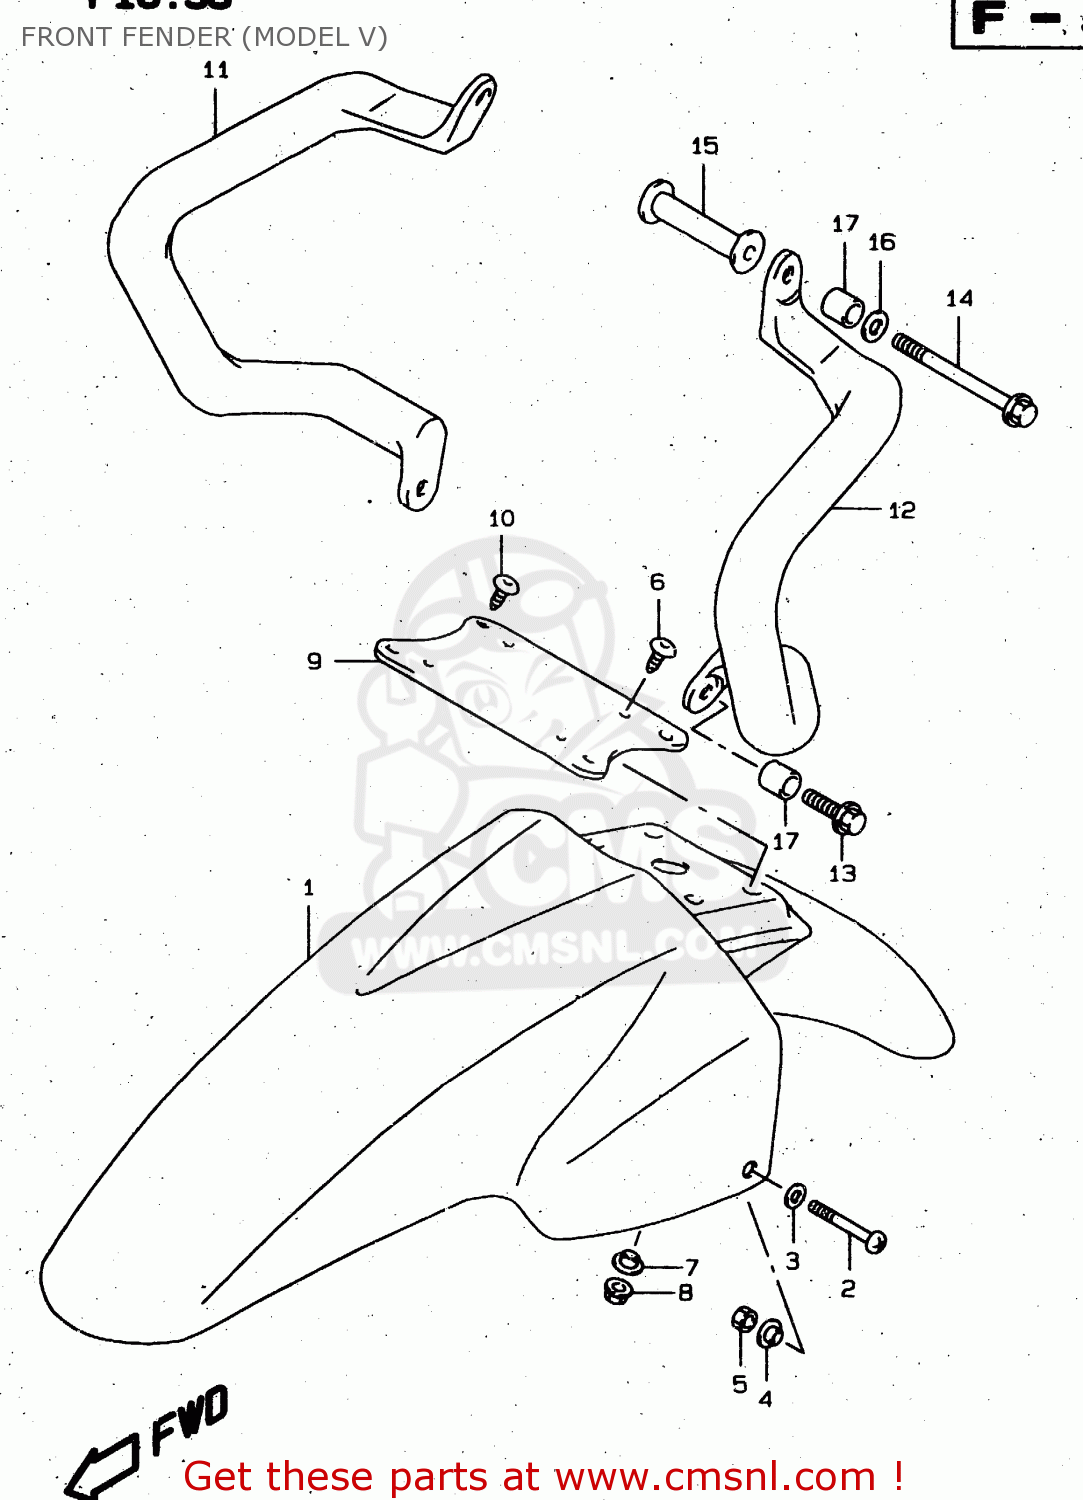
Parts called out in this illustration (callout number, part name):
1	FENDER,FR
2	SCREW
3	WASHER(6.5X18X1.6)
4	WASHER
5	NUT
6	SCREW(5X16)
7	WASHER
8	NUT
9	BRACE,FR FENDER
10	BOLT, BRACE
11	BAR,EXTERIOR,R
12	BAR,EXTERIOR,L
13	BOLT 6X16
14	BOLT
15	SPACER,EXTERIOR BAR,L
16	WASHER(6.5X18X1.6)
17	SPACER(6.1X8X7)
